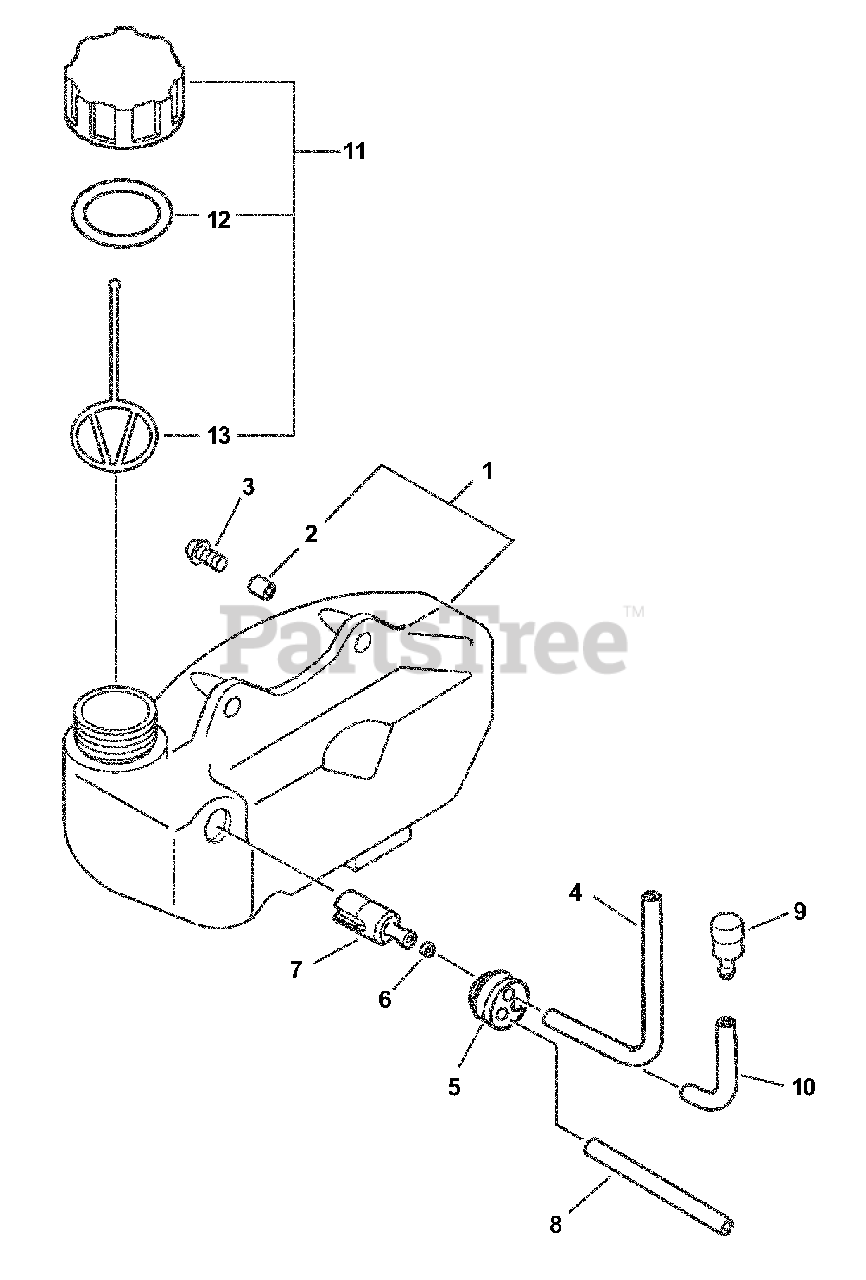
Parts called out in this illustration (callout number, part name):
1	FUEL TANK ASSY
3	SCREW - 5X15
4	PIPE - 3X5X195 -- BLACK
5	GROMMET
6	CLIP - 6
7	FILTER, FUEL
8	PIPE - 3X6X110 -- CLEAR
9	VENT, FUEL TANK
10	PIPE - 3X5X70 -- BLACK
11	CAP ASSY - ORANGE
12	GASKET, CAP
13	CONNECTOR, CAP
